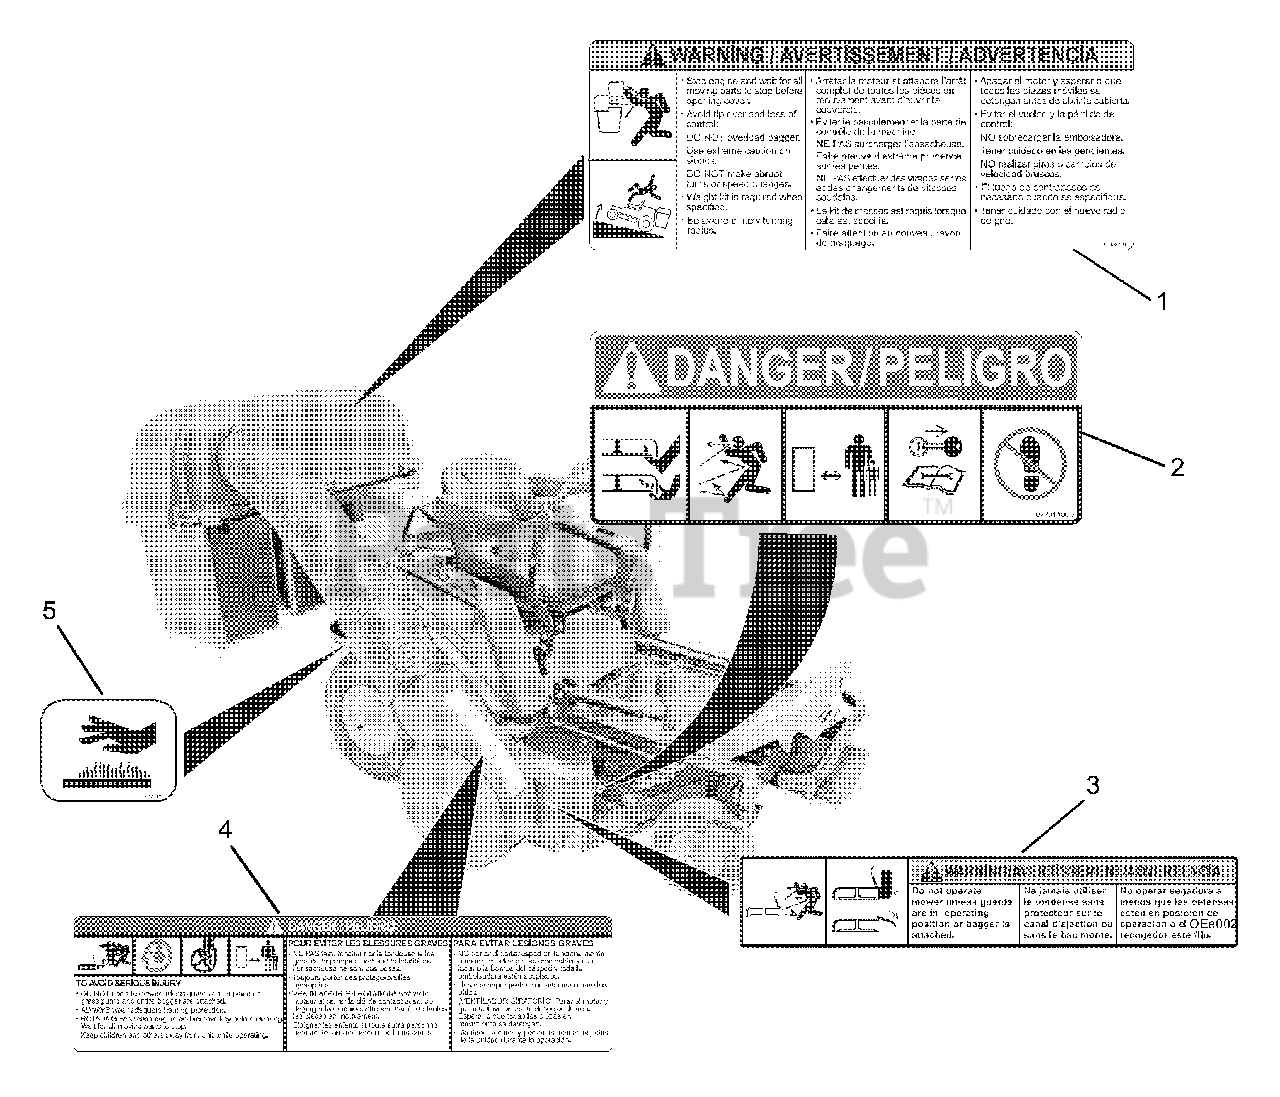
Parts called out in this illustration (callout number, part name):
1	DECAL, BAGGER COVER
2	DECAL, MOWER PAN DANGER
3	DECAL, WARNING
4	DECAL-CAUTION, GRASS PUMP
5	DECAL, HOT SURFACE
